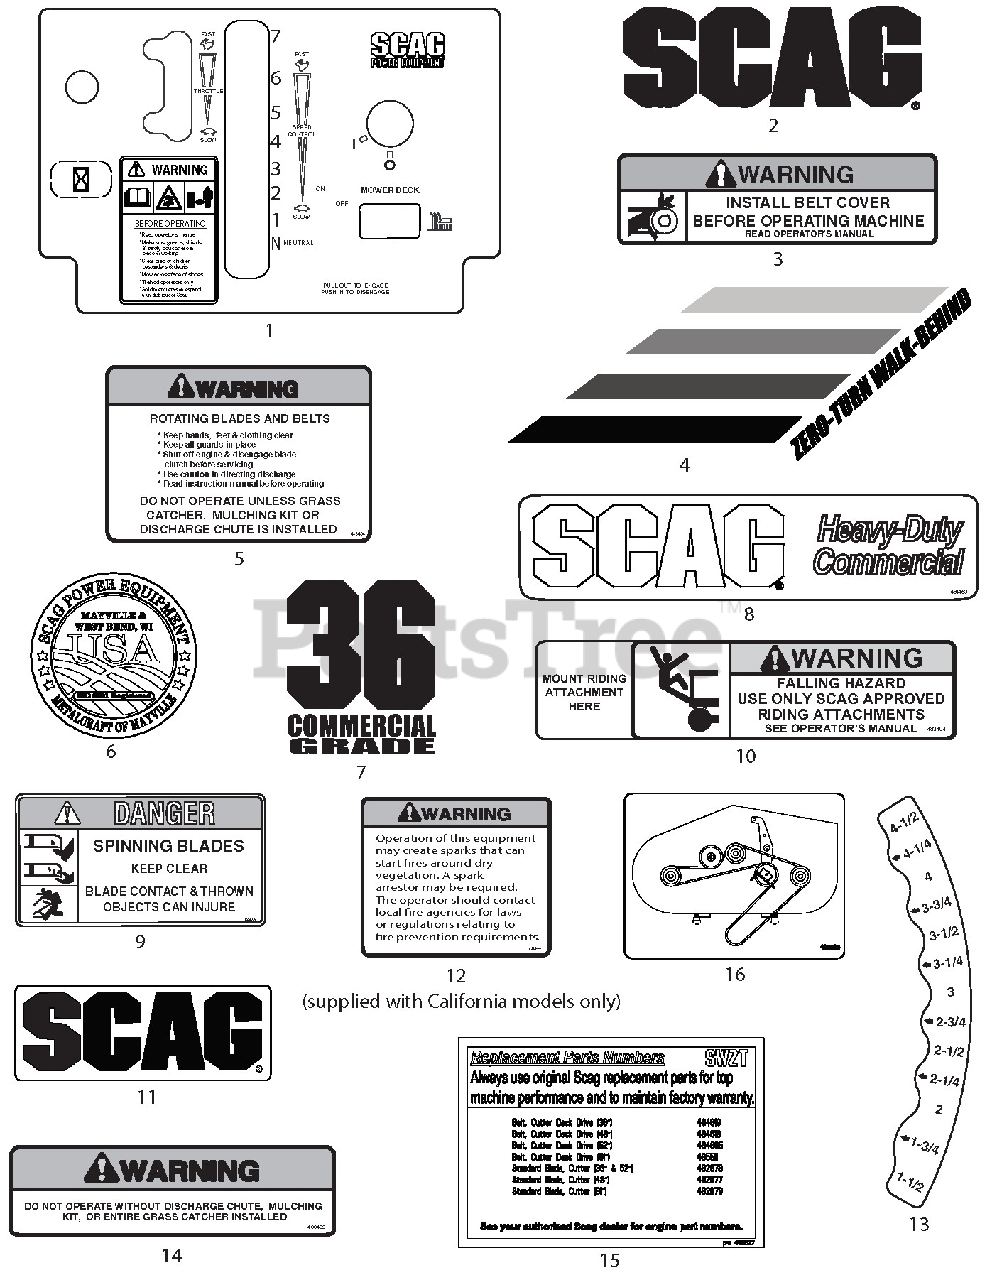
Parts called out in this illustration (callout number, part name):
1	Decal, Instrument Panel (Manual Start)
1	Decal, Instrument Panel (Electric Start Only)
2	Decal, Scag Logo
3	Decal, Belt Cover
4	Decal, Handle - LH
4	Decal, Handle - RH
5	Decal, Warning-Rotating Blades
6	Decal, Metalcraft - USA
7	Decal, 36 Commercial
7	Decal, 48 Commercial
7	Decal, 52 Commercial
8	Decal, Scag Heavy Duty
9	Decal, Spinning Blades
10	Decal, Sulky Attachment
11	Decal, Scag Logo
12	Decal, Warning Spark Arrestor
13	Decal, Height of Cut
14	Decal, Warning
15	Decal, SWZT Replacement Parts
16	Decal, Belt Routing
